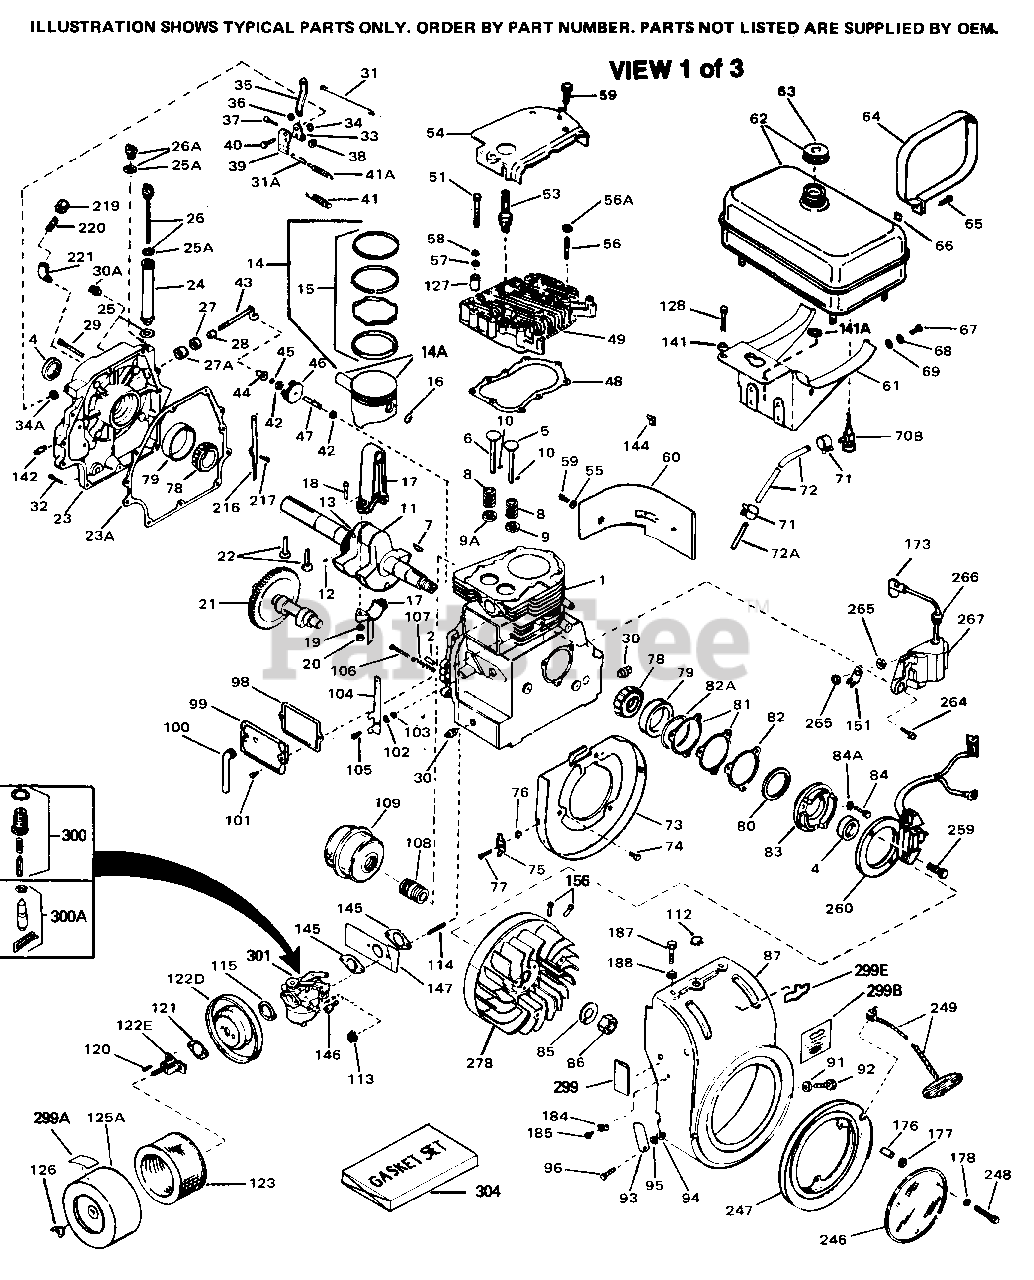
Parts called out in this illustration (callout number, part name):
1	"Cylinder (Incl. 2,4,30,47,119) 3-5/16 "
2	Dowel Pin
4	Seal, Oil
5	Intake Valve (Std.)
5	Intake Valve (1/32" OS) (Incl. 9)
6	Exhaust Valve (Std.)
6	Exhaust Valve (1/32" OS) (Incl. 9)
7	Key, Flywheel
8	Spring, Valve
9	Cap, Lower valve spring (1/32" OS)
9	Cap, Lower valve spring (Std.)
9A	Cap, Lower valve spring (Std.)
9A	Cap, Lower valve spring (1/32" OS)
10	Pin, Valve spring retainer
11	Crankshaft (Incl. 12, 13, 78 & 79)
12	Pin, Crankshaft gear
13	Gear, Crankshaft
14	Piston & Pin Ass'y. (.040" OS) Incl. 16
14	Piston, Pin & Ring Set (Std.) 3-5/16 " Bore
14	Piston, Pin & Ring Set (.010" OS)
14	Piston, Pin & Ring Set (.020" OS)
14	Piston, Pin & Ring Set (.040" OS)
14	Piston, Pin & Ring Set (.030" OS)
14A	Piston & Pin Ass'y. (Std.)(Incl. 16) 3-5/16"
14A	Piston & Pin Ass'y. (.010" OS) Incl. 16
14A	Piston & Pin Ass'y. (.020" OS) Incl. 16
14A	Piston & Pin Ass'y. (.030" OS) Incl. 16
15	Ring Set (Std.) (3-5/16" Bore)
15	Ring Set (.010" OS)
15	Ring Set (.020" OS)
15	Re-Ringing Set, Piston
15	Ring Set (.030" OS)
15	Ring Set (.040" OS)
16	Ring, Piston pin retaining
17	Connecting Rod Ass'y. (Std.) Incl. 18 , 19 & 20
17	Connecting Rod Assy. (.010" US) Incl. 1 8,19,20
17	Connecting Rod Assy. (.020" US) Incl. 1 8,19,20
18	Bolt, Connecting rod
20	Nut Assy., Lock
21	Camshaft (MCR)
22	Lifter, Valve
23	Cylinder Cover Incl. 4,25,26A,28,30,3 4 & 43
23A	* Gasket, Cylinder cover
25A	* Gasket, Oil fill
25A	"O" Ring
26	Dipstick (Incl. 25A)
28	Spacer, Governor rod
29	Screw, 1/4-20 x 2"
30	Oil Drain Plug
31	Link, Governor
32	Screw, 1/4-20 x 1"
33	Clamp, Governor lever
34	Retaining Ring
35	Lever, Governor adjusting
36	Lockwasher
37	Screw, 10-24 x 7/8"
38	Nut, 10-24
39	Plate, Governor spring
40	Screw, 10-32 x 1/2"
41	Spring, Governor
42	Washer, Flat
43	Rod Assy., Governor
44	Spool, Governor
45	Retaining Ring
46	Gear Assy., Governor
47	Shaft, Mechanical Governor
48	* Gasket, Cylinder head
49	Head, Cylinder
51	Screw, 5/16-18 x 5/8" Use as require d
51	Screw, 5/16-18 x 2-3/8" Use as requir ed
51	Screw, 5/16-18 x 1-3/4" Use as requir ed
51	Screw, 5/16-18 x 2" (Use as required)
51	Screw, 5/16-18 x 2-1/4" Use as requir ed
51	Screw, 5/16-18 x 2-1/2" Use as requir ed
51	Screw, 5/16-18 x 1-5/8" Use as requir ed
53	Plug, Spark (D-21)
54	Cover, Cylinder
57	Washer, Flat (Use as required)
58	Washer, Lock (Use as required)
58	Washer, Belleville (Use as required)
59	Screw, 10-24 x 1/2"
60	Extension, Blower housing
63	Fuel Cap (Kerosene)
63	Fuel Cap (Red Plastic) (Spurt resista nt, High profile) (Use as required)
63	Fuel Cap (White Plastic)(Std.) As req uired
64	Strap, Fuel tank
65	Screw, 1/4-20 x 1"
66	Nut, Flange whiz-lock, 1/4-20
67	Screw, T-30, 1/4-20 x 1/2"
67	Screw, 1/4-20 x 27/32" Use as requir ed
67	Screw, 1/4-20 x 5/8" Use as required
67	Screw, 5/16-18 x 7/8" Use as require d
70B	Strainer & Shut-off, Fuel
71	Fuel Line Clamp
72	Fuel Line (8.62") equired)
72	Fuel Line (Braided) (16") Use as requ ired
72	Fuel Line (Braided) (32") Use as requ ired
72	Fuel Line (Braided) (48") Use as requ ired
73	Baffle, Blower housing
74	Screw, 1/4-20 x 5/8"
75	Terminal
76	Breather Tube Grommet
77	Screw, 8-32 x 3/8"
78	Bearing, Tapered roller
79	Cup, Bearing
80	Spacer, Steel (.010" thick) NOTE: De termine the gap between the cover and the machined surface on the cylinder which can be from .001"up to .007" i n which case no shim gaskets will be required. Use of gasket must be limi ted to a combined total o
81	* Gasket, Shim (.004/.005 thick) NOTE: Determine the gap between the cover and the machined surface on the cylin der which can be from .001"up to .007 " in which case no shim gaskets will be required. Use of gasket must be l imited to a combined tot
82	* Gasket, Shim (.005/.007 thick) NOTE: Determine the gap between the cover and the machined surface on the cylin der which can be from .001"up to .007 " in which case no shim gaskets will be required. Use of gasket must be l imited to a combined tot
82A	"O" Ring
83	Cover, Cylinder NOTE: Determine the gap between the cover and the machine d surface on the cylinder which can b e from .001"up to .007" in which case no shim gaskets will be required. U se of gasket must be limited to a com bined total of .010" thi
84	Screw, 10-32 x 1"
84A	Lockwasher, 5/16" (Use as required)
85	Washer, Lock
86	Nut, Flywheel, 3/4-16
87	Blower Housing
91	Washer, Lock
92	Screw, 5/16-24 x 3/8"
93	Switch, Stop
94	Washer, Shakeproof
96	Screw, 5/16-24 x 9/16"
98	* Gasket, Breather
99	Breather Assy.
100	Breather Tube
101	Screw, 10-24 x 1/2"
103	Bushing, Control lever
104	Lever, Control
105	Screw, 10-24 x 5/8"
106	Screw, 10-24 x 2"
109	Muffler
112	Plug, Button (Use as required)
115	* Gasket, Air cleaner
120	Screw, 10-32 x 5/8"
121	Spacer, Air cleaner
125A	Cover, Air cleaner
126	Nut, Wing
128	Screw, 5/16-18 x 3/4" Use as require d
128	Screw, 5/16-18 x 5/8" Use as require d
128	Screw, 5/16-18 x 7/8" Use as require d
141A	Lockwasher, Split (Use as required)
145	* Gasket, Carburetor
146	Screw, 1/4-20 x 1"
147	Baffle, Air
156	Trigger Pin Kit (Use as required)
173	Cover, Spark plug (Use as required)
176	Spacer, Screen
177	Washer, 1/4 plain (Use as required)
178	Lockwasher
178	Washer, Flat 1/4 (Use as required)
184	Conduit Clip
185	Screw, 10-32 x 3/8"
246	Screen, Starter pulley
247	Pulley, Starter
248	Screw, 1/4-20 x 1-1/2"
249	Rope Assy., Starter (Use as required)
266	Grommet, Lead wire
278	Flywheel
299	Decal, Instruction
299A	Decal, Air cleaner
299B	Decal, Solid State
299B	Decal, Name
300A	Inlet Needle, Seat & Clip Assy.
301	Carburetor (Incl. 145) (Refer to Divi sion 5, Section A, page 134 for break down)
304	* Gasket Set (Incl. items marked *)
